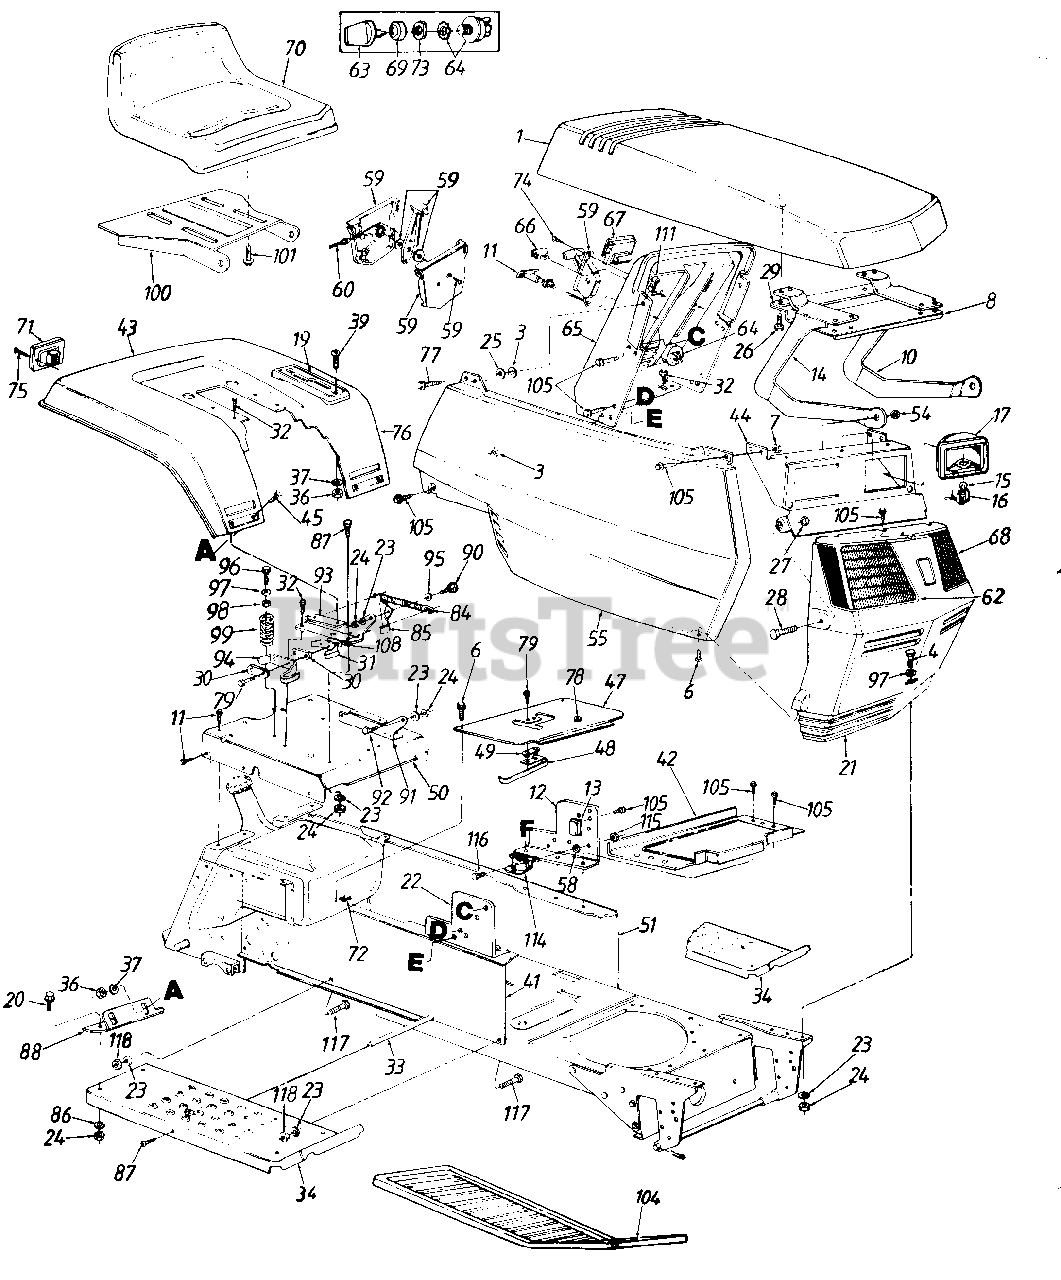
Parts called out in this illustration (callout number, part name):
4	Hex Bolt 5/16-18 x .75" Lg.
6	Truss Mach. B-Tap Scr. #10 x .5" Lg.
7	Hex Patch L-Nut 1/4-20 Thd.
8	Hood Reinforcement
10	Hood Hinge L.H.
11	Choke Control
12	Dash Support Brkt. L.H.
13	Circuit Breaker
14	Hood Hinge R.H.
15	Lamp
16	Twist Lock Lamp Socket
17	Headlight Housing
19	Speed Control Index Brkt.
20	Hex Bolt 5/16-18 x 1.0" Lg.
23	L-Wash. 5/16" I.D.
24	Hex Nut 5/16-18 Thd.
25	Fl-Wash. 1/4" I.D. x .93" O.D.
26	Hex Wash. Hd. B-Tap Scr. 1/4 x.62" Lg.
27	Hex Jam Nut 5/16-18 Thd.
28	Hex Bolt 5/16-18 x 7/8" Lg.
31	Safety Switch (Seat)
32	Hex Wash. Hd. AB-Tap Scr. 5/16 x .75" Lg.
33	Running Board Rod
37	L-Wash. 1/4" I.D.
39	Truss Mach. Scr. 1/4-20 x 1.0" Lg.
41	R.H. Side Frame
42	Battery Support Brkt.
47	Transmission Panel
48	Reverse Safety Switch
49	Insulator Nut Plate
50	Seat Plate
51	L.H. Side Frame
54	Hex Cent. L-Nut 5/16-18 Thd.
55	Side Cover R.H.
58	Ext. L-Wash. 1/4" I.D.
59	Throttle Control Box Ass'y.
60	Throttle Control Wire 35" Lg.
62	Lens R.H.
63	Ignition Key
64	Ignition Switch
65	Dash Panel
66	Light Switch
67	Ammeter
68	Lens L.H.
69	Ignition Switch Cap
70	Seat Ass'y.
71	Taillight Ass'y.
72	Speed Nut #10Z
73	Ignition Switch Nut
74	Truss Mach. AB-Tap Scr. #10 x .5" Lg.
75	Truss Hd. AB-Tap Scr. #6 x .62" Lg.
76	Trim Strip 81" Lg.
77	Hex Wash. Hd. Tap Scr. 1/4 x.75" Lg.
78	Snap Bushing
79	Hex Wash. Hd. AB-Tap Scr. #8 x .50" Lg.
84	Ext. Spring 5.31" Lg.
85	Seat Lift Brkt.
86	Bell-Wash. .345" I.D. x .88" O.D.
87	Truss Machine Scr. 5/16-18 x .75" Lg.
95	Spr.-Wash. .445" I.D.
96	Hex Wash. Hd. Tap Scr. 5/16-18 x .75" Lg.
97	Fl-Wash. .344" I.D.
98	Bushing
99	Compression Spring
100	Seat Pivot Bracket
101	Hex Tap Scr. 3/8-16 x .75"
104	Foot Pad
105	Hex Tap Scr. 1/4-20 x .5" Lg.
108	Insulator Boss Plate
111	Speed Nut 1/4-20 Thd.
114	Solenoid
115	Hex Sems Nut 1/4-20 Thd.
116	Hex Bolt 1/4-20 x .5" Lg.
117	Rib Neck Bolt 5/16-24 x .75" Lg.
118	Hex Nut 5/16-24 Thd.
